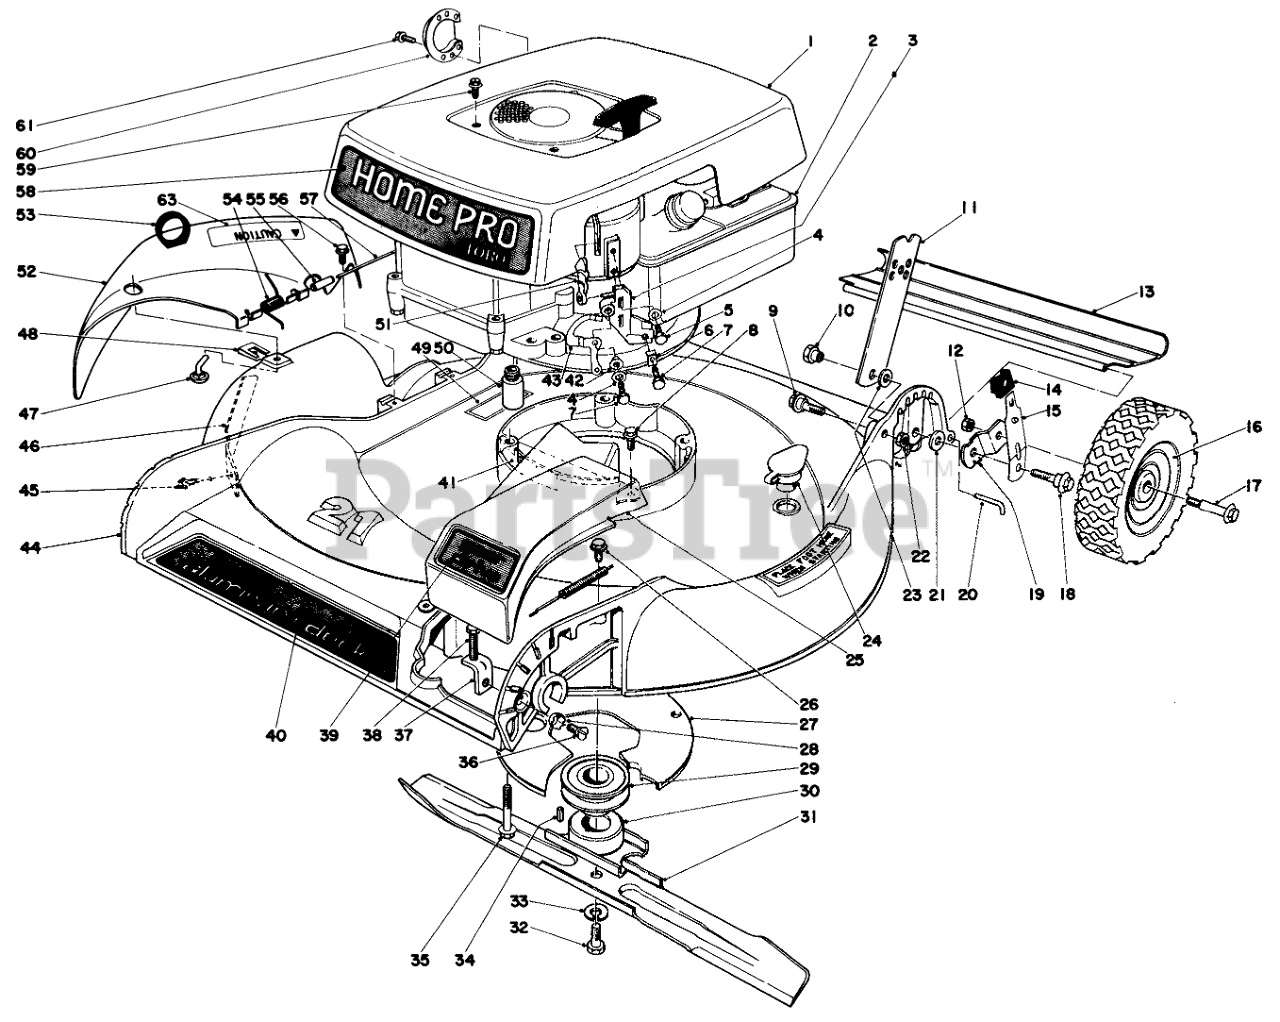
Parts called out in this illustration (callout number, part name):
1	Shroud
2	Engine
3	CABLE & PIVOT BLOCK
4	WASHER-FLAT
5	Screw
6	CLAMP
7	SCREW-HWHTF
8	SCREW
9	SCREW-SHOULDER
10	HANDLE PIVOT NUT
11	HANDLE LATCH
12	Nut
13	SHIELD - TRAILING
14	KNOB-ARM
15	SPRING ARM ASM
16	Wheel Assembly
18	PIVOT SCREW
19	PIVOT ARM PLATED
20	SHIELD ROD
21	WASHER-PIVOT
22	Nut
23	HANDLE LATCH SPACER
24	WASHOUT PLUG
25	Cover Belt Drive
26	SCREW-HWHTF
27	Grass Guard
28	Lockwasher
29	Pulley
30	Blade Retailer
31	Blade
32	SPECIAL SCREW
33	WASHER-LOCK
34	KEY-SQUARE
35	3/8-16 X 2-3/4 CAPSCR
37	Bracket-Gear Box
38	SCREW-HH
39	Decal Gear Drive
40	Decal Deck
41	HOUSING CAP
42	BUSHING
43	CAM INTERLOCK
44	Housing (Incl. Ref. #40 & 49)
45	Screw Thread Forming
46	Bar Safety
47	BAG CHUTE PIN
48	BAG CHUTE CLIP PIN
49	Decal Warning
50	OIL DRAIN EXTENSION
51	INTERLOCK LEVER
52	Deflector
53	LIFT LOOP
54	TORSION SPRING
55	SLEEVE
56	SCREW
57	HINGE PIN
58	Decal Shroud
59	8X1/2 SELF TAP SCREW
60	Deflector
61	SCREW W/ENGINE
63	Caution Decal
